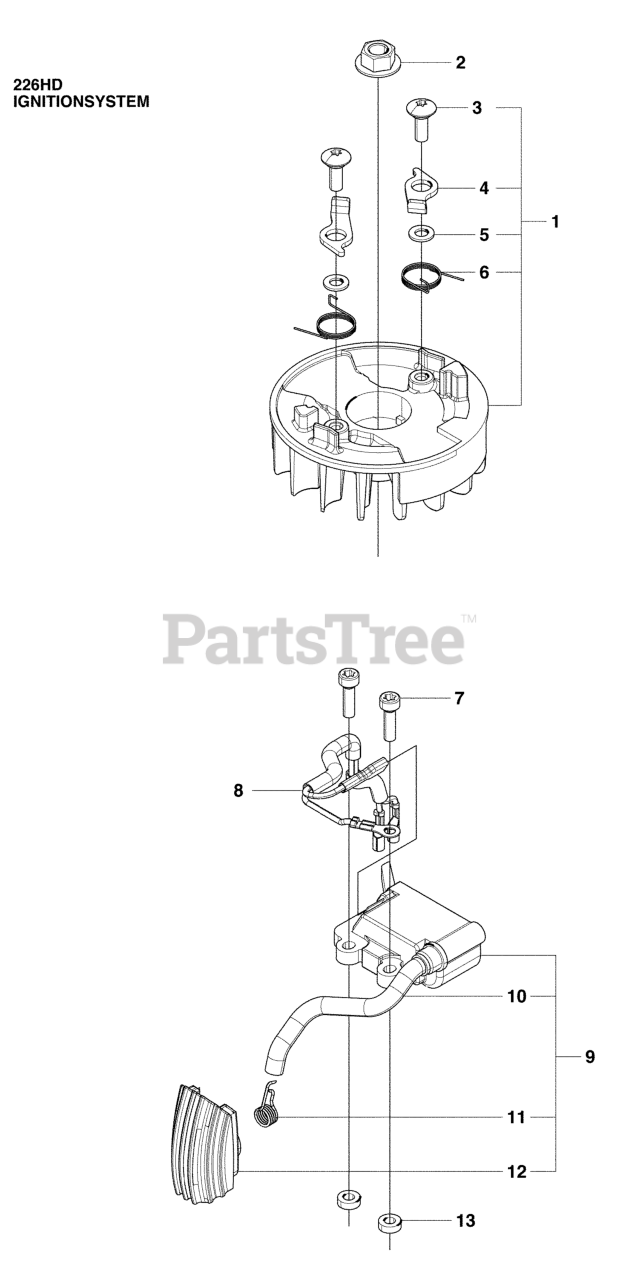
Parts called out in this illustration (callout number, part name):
1	ROTOR ASSY
2	RP NUT
7	BOLT TORX M4XL16 T27
9	COIL ASSY
13	SPACER
